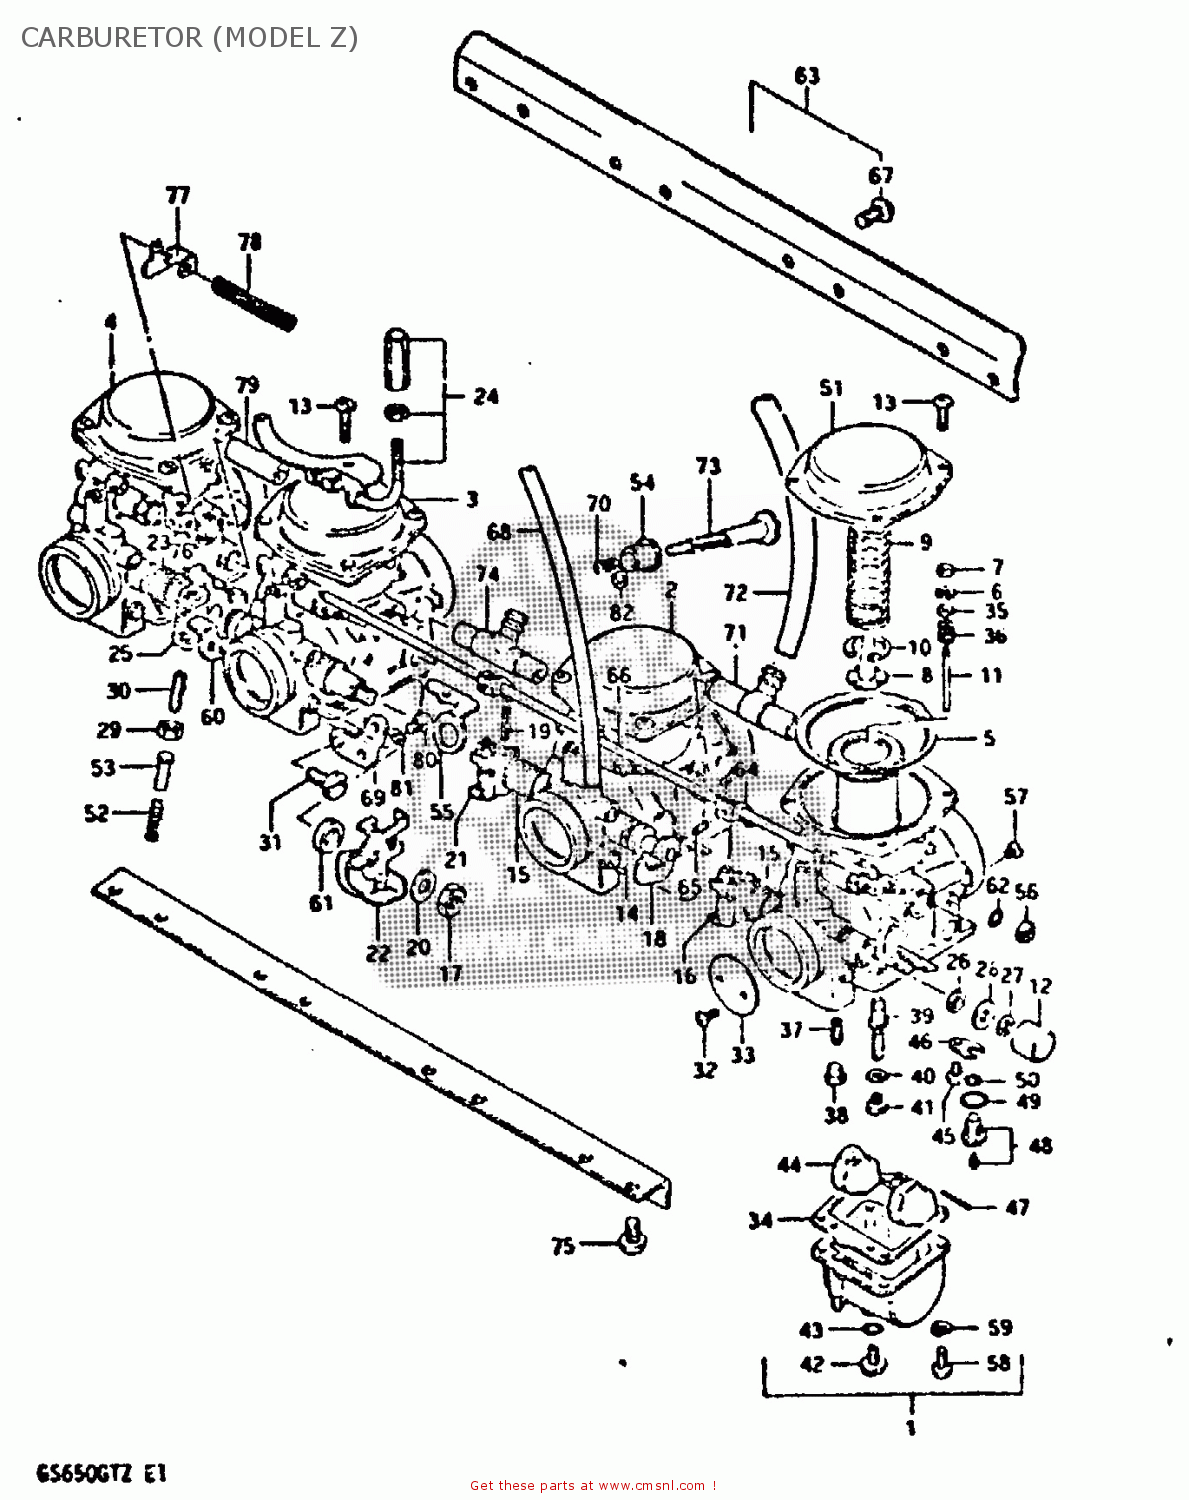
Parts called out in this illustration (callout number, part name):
1	CARBURETOR, LH
2	CARBURETOR, ML
3	CARBURETOR, MR
4	CARBURETOR, RH
5	DIAPHRAGM
6	CLIP,NEEDLE
7	RING
8	HOLDER,GUIDE
9	SPRING
10	E RING
11	NEEDLE, JET (5C41-3)
12	CAP
13	SCREW
14	GASKET,THROTTLE SHAFT (NAS)
15	SPRING,THROTTLE SHAFT
16	SHAFT,THROTTLE
17	NUT 8MM
18	SHAFT,THROTTLE
19	PIN,THROTTLE SHAFT
20	WASHER
21	LEVER,THROTTLE SHAFT
22	LEVER ASSEMBLY,THROTTLE
23	SPRING,THROTTLE SHAFT
24	BRACKET,THROTTLE CABLE
25	SHAFT,THROTTLE
26	SEAL
27	E RING
28	GASKET,THROTTLE SHAFT (NAS)
29	NUT
30	SCREW
31	SCREW
32	SCREW
33	VALVE,THROTTLE (BUTTERFLY)
34	GASKET,FLOAT CHAMBER (NAS)
35	WASHER
36	SPRING
37	JET, PILOT (42.5)
38	PLUG,NEEDLE JET
39	JET, NEEDLE (Y-7)
40	WASHER,NEEDLE NOZZLE
41	JET, MAIN
42	PLUG,DRAIN
43	GASKET (NAS)
44	FLOAT
45	SCREW 4X6
46	PLATE,NEEDLE VALVE FITING
47	PIN,FLOAT
48	VALVE ASSEMBLY,NEEDLE
49	O-RING,NEEDLE VALVE
50	FILTER
51	COVER,DIAPHRAGM
52	SPRING,THROTTLE SCREW
53	PIN,THROTTLE LEVER
54	BUSH
55	BRACKET,THROTTLE ADJUST
56	CAP,STARTER VALVE
57	JET,AIR(140)
58	SCREW
59	LOCK WASHER
60	SHAFT,THROTTLE
61	WASHER
62	O RING
63	CARBURETOR ASSEMBLY
64	LEVER
65	SCREW
66	SHAFT,STARTER
67	SCREW
68	HOSE
69	BRACKET,THROTTLE ADJUST
70	SPRING
71	NIPPLE
72	HOSE
73	SCREW
74	NIPPLE,CARBURETOR
75	SCREW 6X12
76	LEVER,CHOKE CABLE
77	PLATE,CHOKE CABLE
78	SPRING,CHOKE CABLE
79	NIPPLE
80	SCREW
81	LOCK WASHER
82	WASHER
